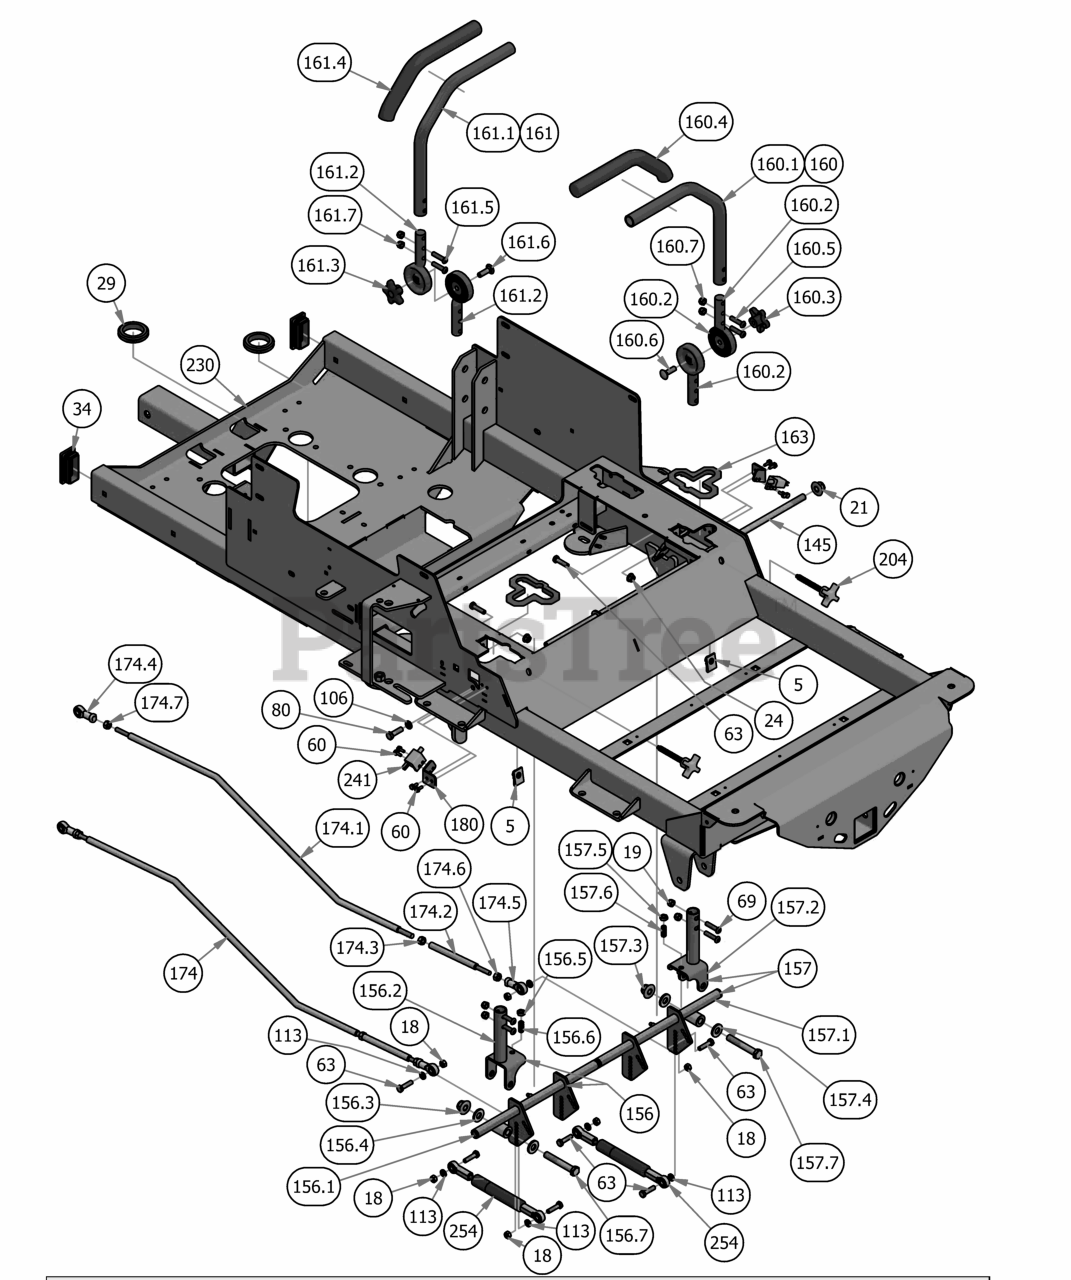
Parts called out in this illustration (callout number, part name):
5	Extruded Nut 3/8"-16 3/4" Hole Center With Patch
19	5/16-18 Nylock Insert Locknut
21	1/2-13 Nylon Flange Nut
24	5/16" Flange Nut
29	2019 2" x .25 Rubber Grommet
34	1 1/2 x 3 Frame Plug
60	12-24x 1/2 HWH Bolt
63	5/16 x 1 1/4 Hex Bolt
69	5/16-18 BHCS, TORX DRIVE
80	3/8" x 1 1/4" Hex Bolt
106	3/8" Lock Washer
113	5/16" Lock Washer
145	2019 Steering Actuator Rod
156	2019 R Series RH Arm Rod Assembly
156.1	2019 Drive Arm Actuator right
156.1.1	2019 Drive Arm Actuator right - Weldment
156.1.2	1/4" Press in Grease Fitting
156.1.3	2019 Drive Arm Bushing
156.2	Drive Arm Pivot
156.3	1/2-13 Nylon Flange Nut
156.4	.505 Nylon Spacer
156.5	3/8-16 Half Jam Nut
156.6	3/8-16 x 1 Set Socket Set Screw Cup Point
156.7	1/2-13 x 3.25 GR 5 Hex Bolt Zinc
157	2019 R Series LH Arm Rod Assembly
157.1	2019 Drive Arm Actuator left
157.1.1	2019 Drive Arm Actuator left - Weldment
157.1.2	1/4" Press in Grease Fitting
157.1.3	2019 Drive Arm Bushing
157.2	Drive Arm Pivot
157.3	1/2-13 Nylon Flange Nut
157.4	.505 Nylon Spacer
157.5	3/8-16 Half Jam Nut
157.6	3/8-16 x 1 Set Socket Set Screw Cup Point
157.7	1/2-13 x 3.25 GR 5 Hex Bolt Zinc
160	2019 Left Hand ADJ. Steering Arm Kit
160.1	2019 Steering Arm Grip
160.2	2019 Steering Arm Adjuster Casting
160.3	Black Knob for Adjustable Steering Arm
160.4	Black Steering Arm Grip
160.5	5/16-18 BHCS, TORX DRIVE
160.6	3/8" x 1 1/4" Carriage Bolt
160.7	5/16-18 Nylock Insert Locknut
161	2019 Right Hand ADJ. Steering Arm Kit
161.1	2019 Steering Arm Grip
161.2	2019 Steering Arm Adjuster Casting
161.3	Black Knob for Adjustable Steering Arm
161.4	Black Steering Arm Grip
161.5	5/16-18 BHCS, TORX DRIVE
161.6	3/8" x 1 1/4" Carriage Bolt
161.7	5/16-18 Nylock Insert Locknut
163	Snap-In Bushing-2019
174	2019 Outlaw Gen2 Horizontal Push Rod Assembly
174.1	2019 Outlaw Gen2 Horizontal Push Rod
174.2	2019 Outlaw Gen2 Horizontal Push Rod Adjuster
174.3	3/8" Fine Threaded Jam Nut
174.4	Spherical Rod End - Outlaw
174.5	Spherical Rod End - Outlaw
174.6	5/16" LH Fine Threaded Jam Nut
174.7	5/16" RH Fine Threaded Jam Nut
180	2019 Arm Switch Bracket
204	Speed Limiting Knob 3/8-16X 3"
230	2019 Horizontal Diesel Frame
241	Safety Switch
254	2019 SROID Damper With Spherical Rod Ends
